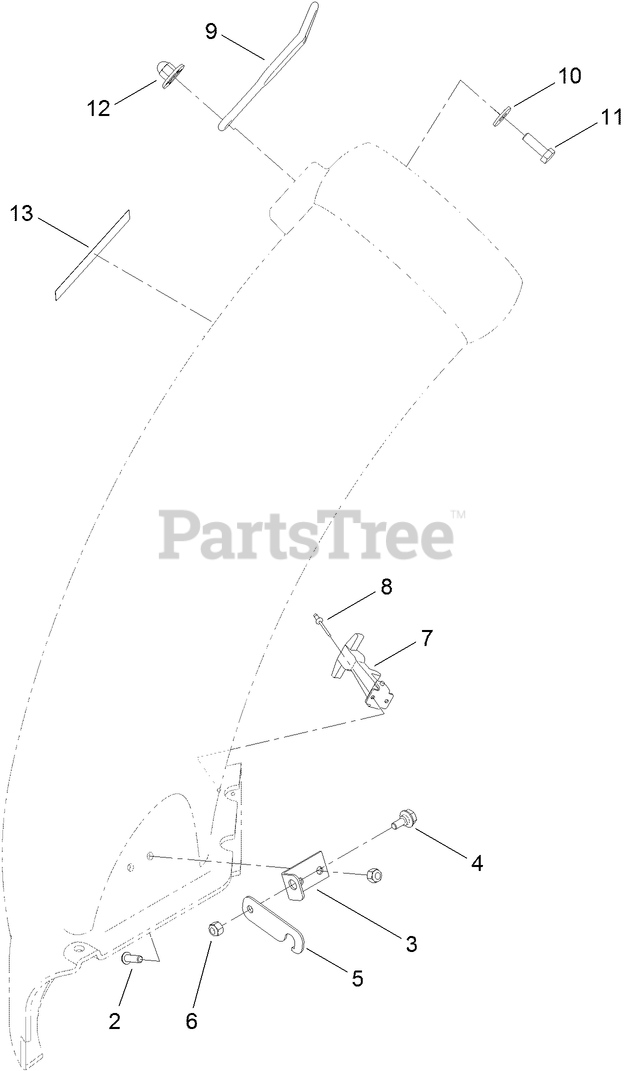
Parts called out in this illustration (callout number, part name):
2	SCREW-HSBH
3	PLATE-PIVOT
4	SCREW-SHOULDER,HWH
6	NUT-LOCK, NI
7	HANDLE ASM
8	RIVET-POP
9	RETAINER-DUCT
10	WASHER-FLAT
11	SCREW-HH
12	NUT-IMPELLER
13	DECAL-DANGER
